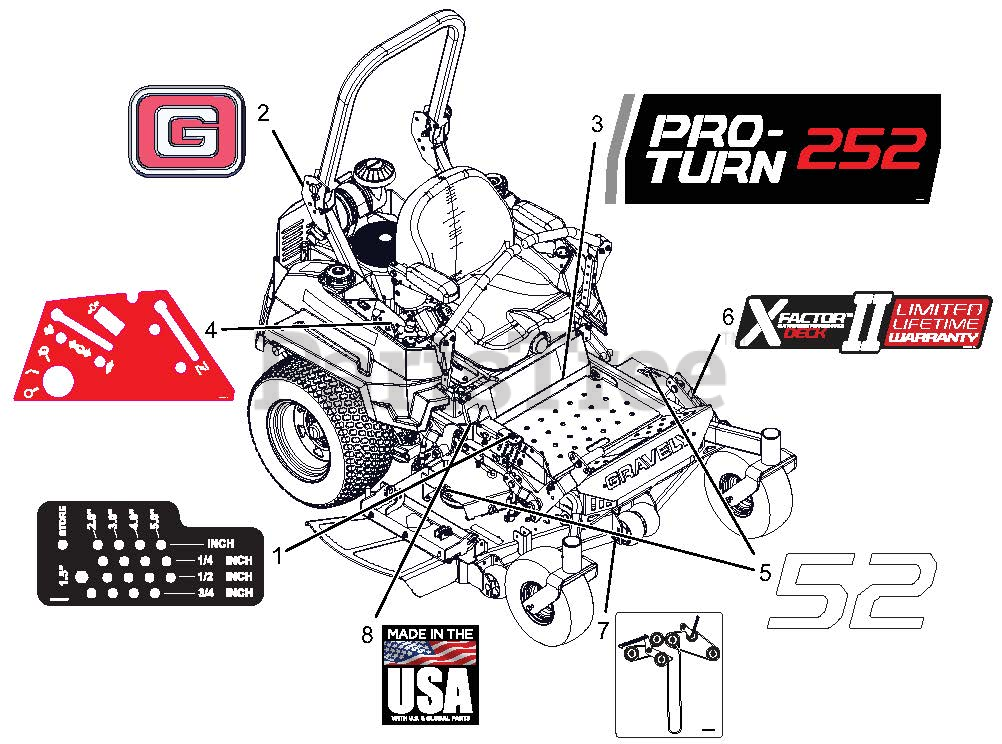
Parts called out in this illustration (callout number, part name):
1	DECAL, HEIGHT OF CUT
2	DECAL, GRAVELY BRAND
3	DECAL, PRO-TURN 252
4	DECAL, NON-EFI CONTROL PANEL
5	DECAL, 52"
6	DECAL, X-FACTOR DECK
7	DCL,BELT ROUTE-RH V-SIDE IDLER
8	DECAL, MADE IN USA
